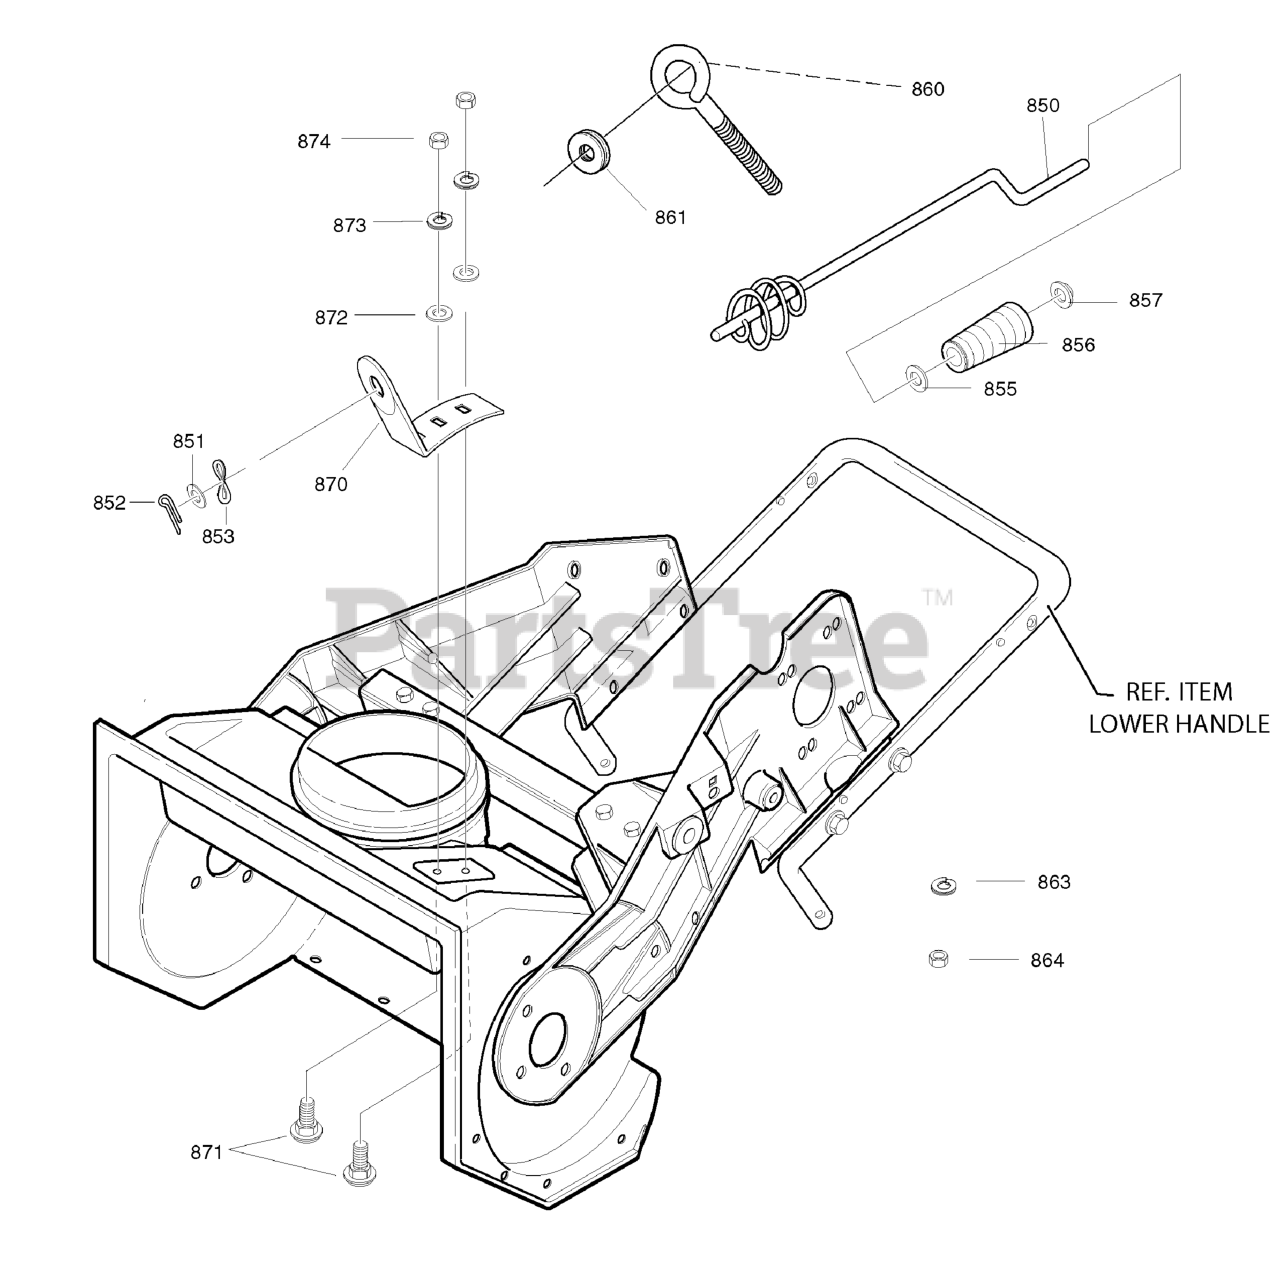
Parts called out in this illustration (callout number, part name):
850	ROD, ASSEMBLY UPPER CHUTE
851	WASHER, Flat, 13/32
852	COTTER PIN
853	WASHER, CURVED SPRING
855	WASHER, Flat, 13/32
856	KNOB, SLEEVE
857	NUT, PUSH
860	EYE BOLT 3/8-16 x 2.00
861	GROMMET, EYE BOLT
863	WASHER, SPLIT LOCK
864	NUT, 3/8-16
870	BRACKET, CHUTE ROTATE
871	BOLT, 5/16-18 x .75
872	FLATWASHER
873	WASHER, SPLIT LOCK
874	NUT, 5/16-18
